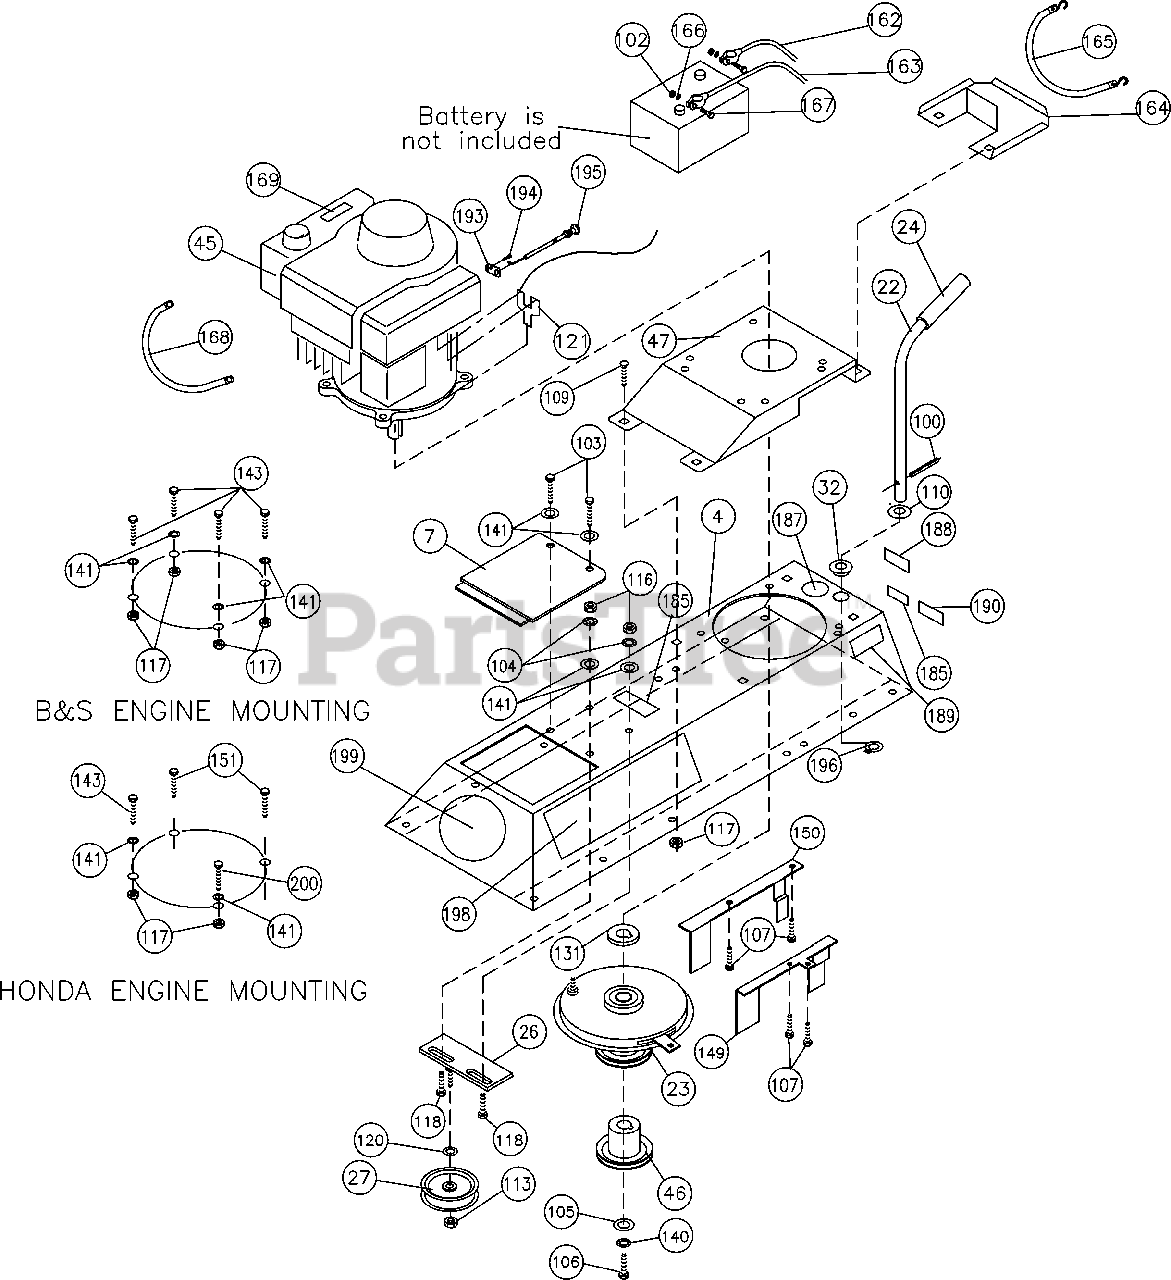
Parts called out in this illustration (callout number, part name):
4	Base Assembly with labels
7	Door Base Engine
22	Tube Shift With Grip
23	Clutch Brake
24	Grip 3/4 ID - Black
26	Plate Mount Idler WA
27	Pulley Idler 4.5" OD X 3/8”
32	Bushing Shifter
45	13 HP Honda GXV390
46	Pulley Drive Traction BC
47	Spacer Engine WA 2401
100	Roll Pin 1/4 x 1 1/4
102	Nut Lock 1/4 - 20
103	Screw Cap 5/16-18 x 1-1/4”
104	Washer Split Lock 5/16”
105	Plate Impeller Washer
106	Screw Cap 7/16-20 X 3"
107	Screw Cap 7/16 - 20 x 2 3/4"
109	Bolt Carriage 5/16-18 x 3/4 “
110	Washer Flat 1/2"
113	Nut Lock 3/8-16
116	Nut Jam 5/16-18
117	Nut Lock 5/16-18
118	Bolt Carriage 5/16-18 x 1”
120	Washer 3/8 FC
121	Terminal Piggyback 3/16
131	Spacer Engine
140	Washer Lock 7/16”
141	Washer 5/16” FC
143	Screw Cap 5/16-18 x 1-3/4”
149	Guide Belt LH
150	Guide Belt RH
151	Screw Cap 5/16-24 x 1”
162	Part Not Applicable on this model
163	Part Not Applicable on this model
164	Part Not Applicable on this model
165	Part Not Applicable on this model
166	Washer 1/4” SAE
167	Screw Cap 1/4-20 x 3/4”
168	Part Not Applicable on this model
169	Label Hot Engine
185	Label Guards
187	Label Read
188	Label Ear Eye Breathe
189	Label Chock Wheels
190	Label Patent No
193	Plate Choke Mount BC
194	Screw Machine 10-32 x 3/4"
195	Control Cable Choke BC
196	Ring Retaining External 3/4”
198	Label Outback BC
199	Label Product Decal
200	Part Not Applicable on this model
